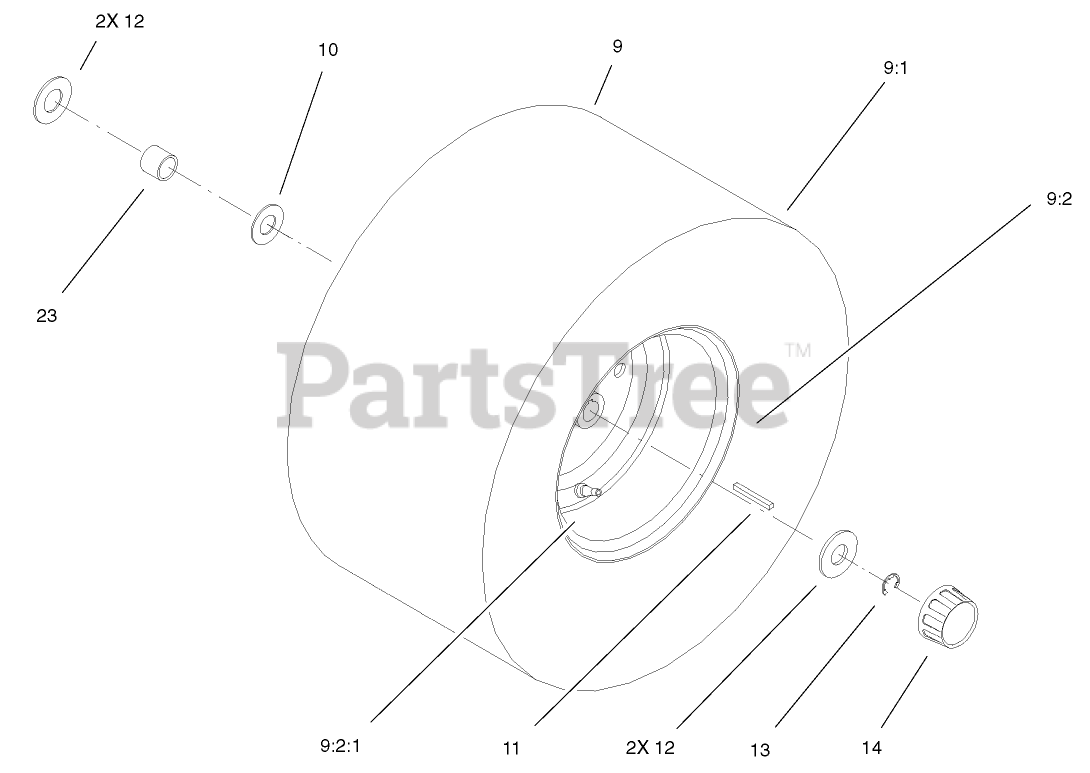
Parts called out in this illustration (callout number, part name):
9	Loose Parts Package
9:1	TIRE
10	WASHER-THRUST
11	KEY-SQUARE
12	WASHER-PLAIN
13	E-RING
14	CAP-HUB
23	SPACER-WHEEL
